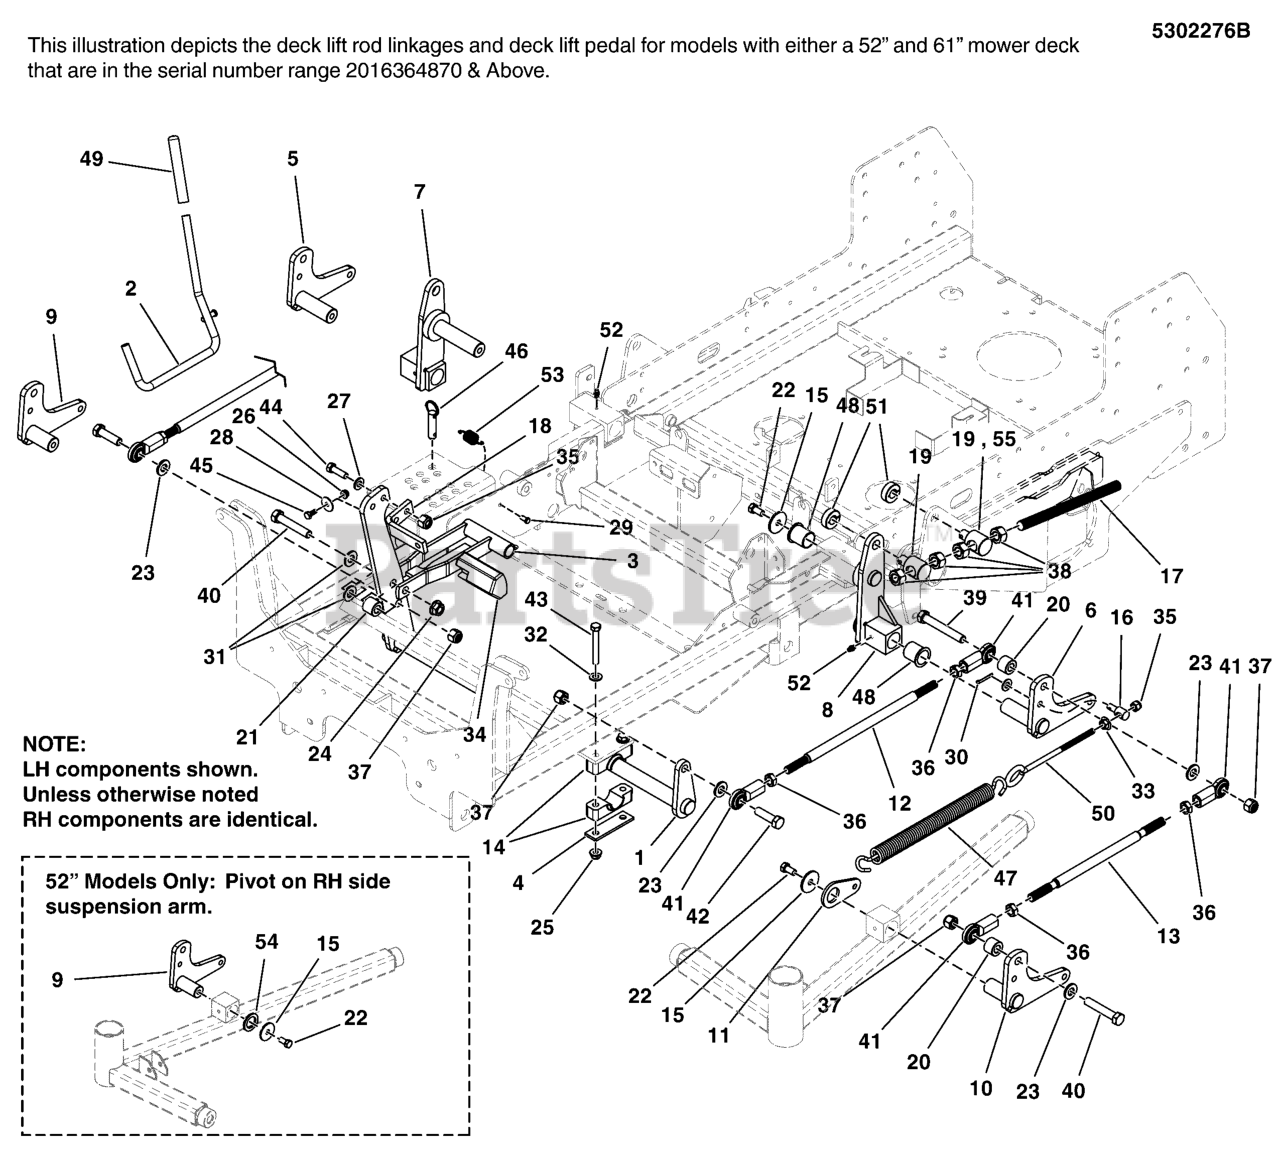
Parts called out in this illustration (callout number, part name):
1	WELD, DECK LIFT SHAFT - RED
2	WELD, Rod, Deck Lift - BLK
4	PLATE, PIVOT BLOCK SUPPORT - BLK
5	WELD, DECK LIFT LEVER, RH - BLK
6	WELD, DECK LIFT LEVER, LH - BLK
7	WELD, REAR LIFT - RH - BLK
8	WELD, REAR LIFT - LH - BLK
9	WELD, DECK LIFT LEVER, RH - RED
10	WELD, DECK LIFT LEVER, LH - RED
11	MOUNT, SPRING, DECK LIFT - RED
12	ROD, DECK LIFT, 19.25, CZ
13	ROD, 1/2-20 X 20.50", CZ
14	PIVOT BLOCK, PLASTIC
15	WASHER, .390 X 1.50 X .109, YZ
16	ADJUSTER, DECK HANGER
17	ROD, 5/8-11 X 9.00
18	PEDAL, FOOT - BLK
19	PIVOT, SPRING ROD
20	SPACER, .52 X 1.00 X .75, CZ
21	SPACER, .52 X 1.00 X .88, CZ
22	BOLT, 3/8-16 X 3/4, PLT W/PATCH
23	WASHER, 1/2 GD9 YZ
24	NUT, Hex Flange, Nylock, 1/2-13
25	NUT, 3/8-16 HEX NYLOCK FLANGE
26	NUT, 1/4-20 HEX NYLOCK FLANGE
27	WASHER, 3/8 GD.9 FLAT
28	WASHER, 1/4 FENDER
29	CLEVIS PIN, 1/4 X 1/2, CZ
30	PIN, COTTER, 1/8 X 3/4
31	WASHER, 1/2 SAE
32	WASHER, 3/8 SAE
33	NUT, 3/8-16 HEX LG. SERR FLG
34	PEDAL, Rubber
35	NUT, 3/8-16 HEX NYLON LOCK
36	NUT, 1/2-20 HEX JAM
37	NUT, 1/2-13 HEX NYLON LOCK
38	NUT, 5/8-11 HEX
39	BOLT, 1/2-13 X 3-1/4, HEX HD, GD5, CZ (SV)
40	BOLT, 1/2-13 X 2-3/4 GD5 CZ
41	JOINT-BALL .500-20 THD .500ID, CLR ZINC
42	BOLT, 1/2-13 X 1-3/4 GD5 CZ
43	BOLT, 3/8-16 X 2-3/4" GD5 CZ
44	BOLT, 3/8-16 X 1-1/4" GD5 CZ
45	HHCS, 1/4-20 X 0.625, GR5, ZINC/CLEAR
46	PIN, HITCH, 1/2 X 2.00 OAL, YP
47	SPRING-EXT, 1.00 ODX13.25LGX.177WR, BLK
48	BUSHING, 1.00 X 1.13 X 1.38, PLASTIC
49	GRIP, FOAM, .475 X 4.35 X .095
50	EYE BOLT, 3/8-16 X 8, 3THRD, 1EYE, CZ
51	COLLAR, 5/8 SPLIT
52	GREASE FITTING, 1/4-28 STRAIGHT
53	SPRING-EXT, .740 ODX2.025LGX.072WR, BLK
54	SHIM, 1.0 X 1.5 X 0.125
55	PIVOT, SPRING ROD
